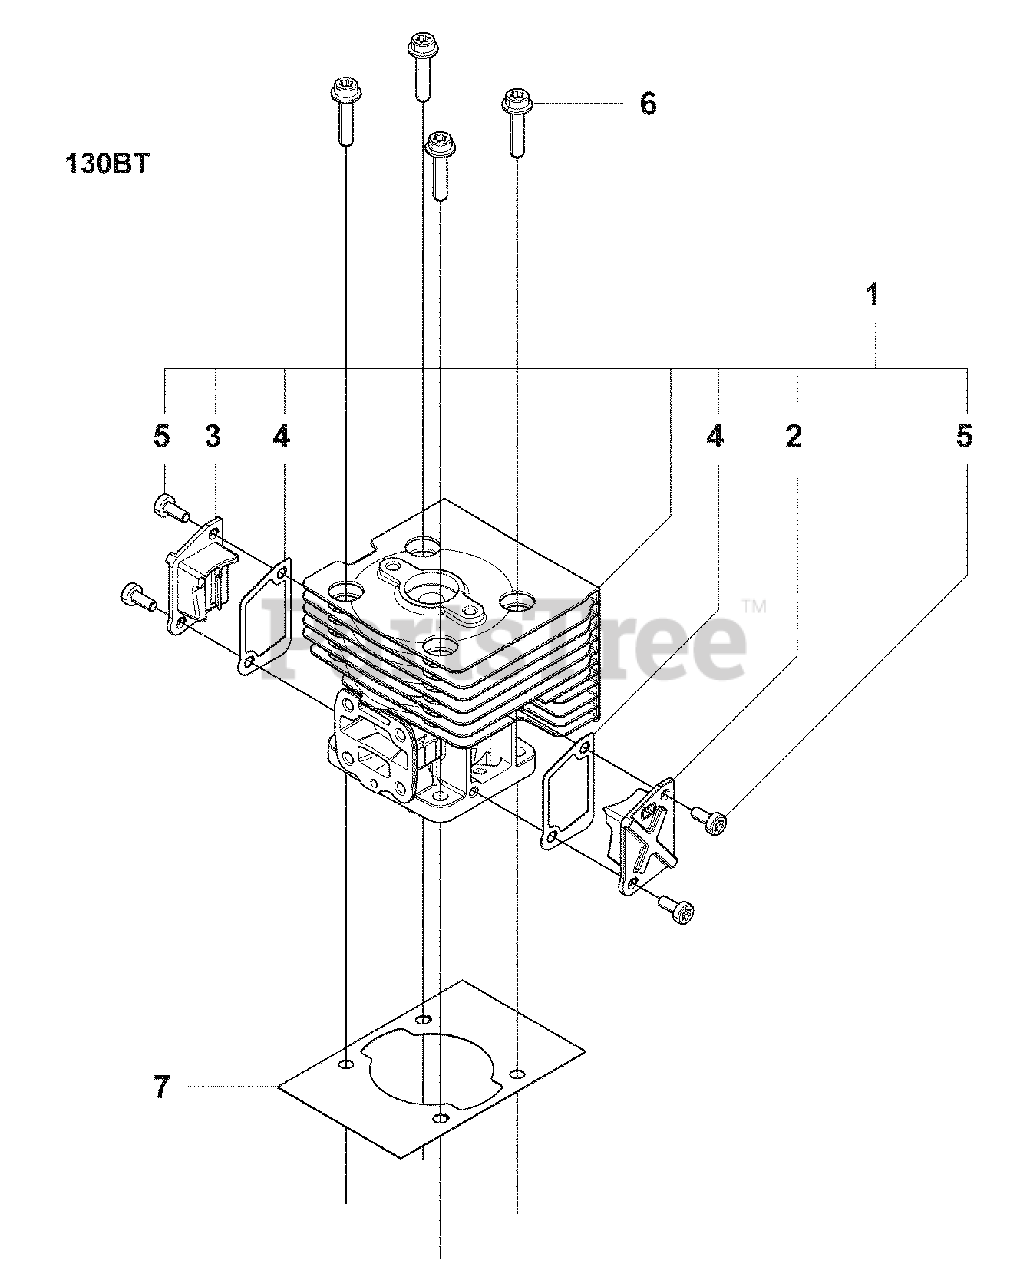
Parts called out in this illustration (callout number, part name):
1	Cylinder
3	Cover, TR F
4	Gasket, TR
6	Torx Bolt
7	Base Gasket
